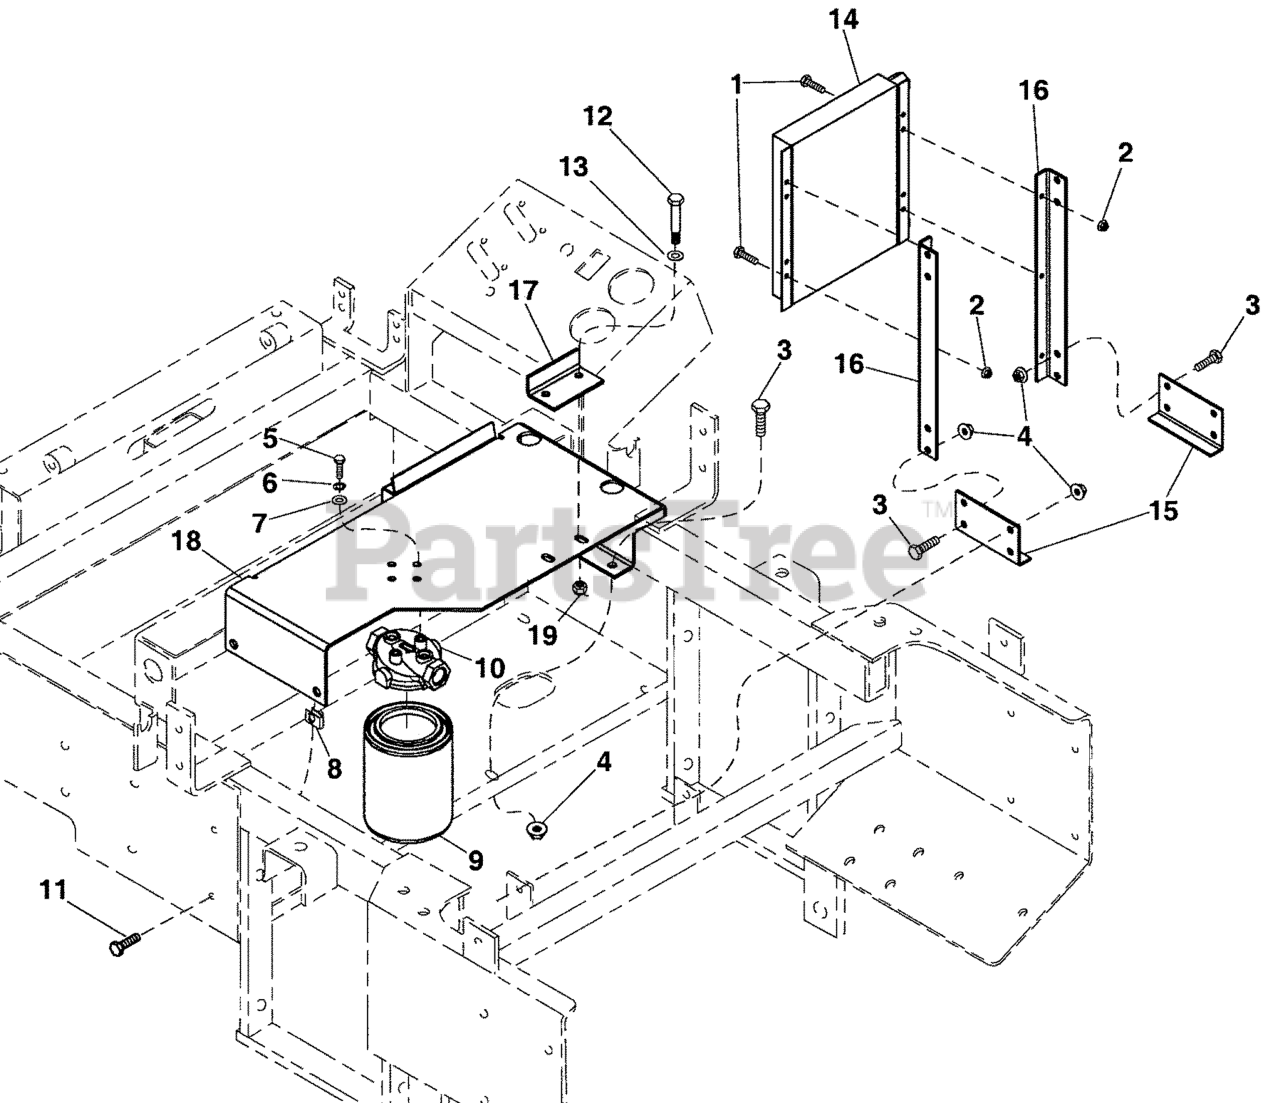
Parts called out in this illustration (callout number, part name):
1	HHCS, 1/4-20 X 0.625, GR5, ZINC/CLEAR
2	NUT, 1/4-20 HEX SERR. FLANGE
3	BOLT, 3/8-16 X 3/4" GD5 CZ
4	NUT, Hex, Serrated Flange, 3/8-16
5	BOLT, 1/4-20 x 3/4
6	WASHER, 1/4 LOCK
7	WASHER, 1/4 SAE
8	BODY CLIP, 5/16-18-7GA MATERIAL
9	FILTER
10	FILTER HEAD
11	BOLT, 5/16-18 x 1
12	BOLT, 5/16-18 x 1-1/2
13	WASHER, 5/16" SAE
14	HYDRAULIC OIL COOLER
15	COOLER BRACKET, Short
16	COOLER BRACKET, Long
17	HOLD DOWN BRACKET
18	BATTERY TRAY
19	NUT, Hex, Nylon Locking, 5/16-18
